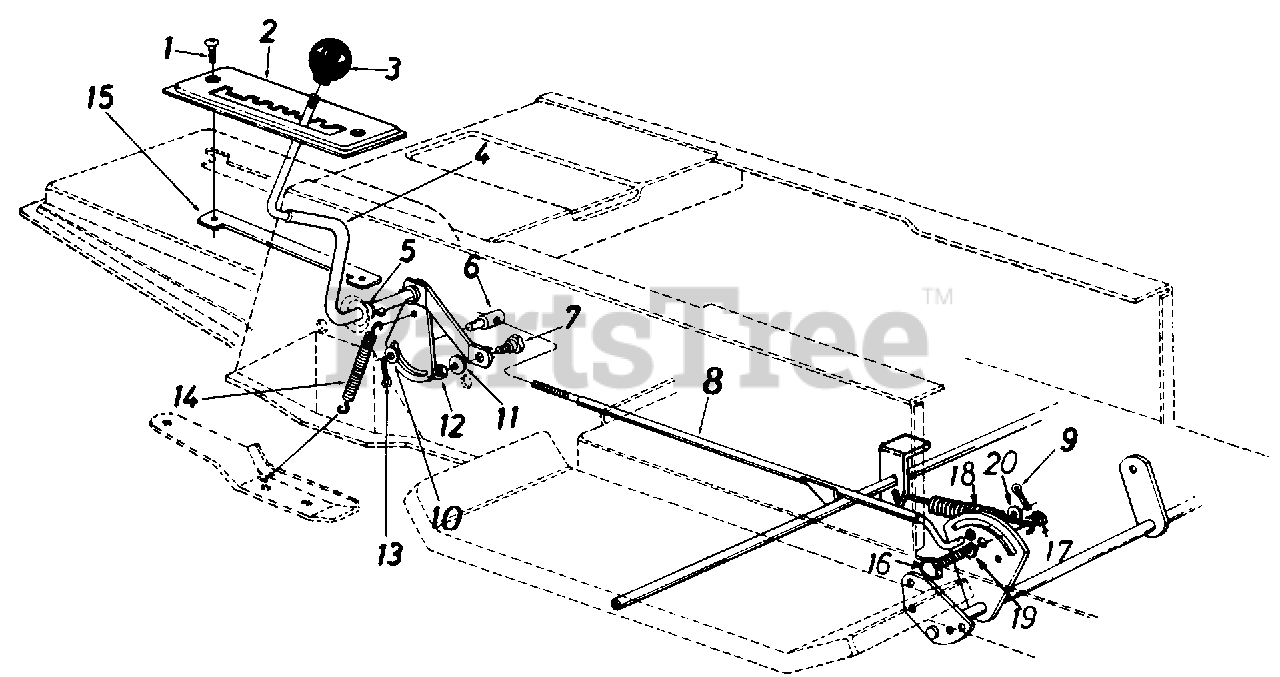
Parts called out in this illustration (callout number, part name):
1	Truss Mach. Scr. 1/4-20 x .75" Lg.
4	Speed Selector Cam Ass'y.
5	Flat Washer .53" I.D. x .93"
6	Ferrule 3/8-24 x .37" Dia.
7	Shoulder Bolt .435" Dia. x .160
8	Speed Control Rod Ass'y.
9	Cotter Pin 3/32" Dia. x .75"
10	Fl-Wash. .385" I.D. x .62" O.D.
11	L-Wash. 5/16" I.D.
12	Hex Nut 5/16-18 Thd.
13	Cotter Pin 3/32 Dia. x .75"
14	Spring
15	Clamping Plate
16	Hex Cap Bolt 5/16-18 x 1" Lg.
17	Hex Cent L-nut 5/16-18 Thd.
18	Ext. Spring .53" O.D. X 4.75" Lg.
19	Hex Nut 5/16-18 Thd.*
20	Fl-Wash. .47" I.D. X .88" O.D.
